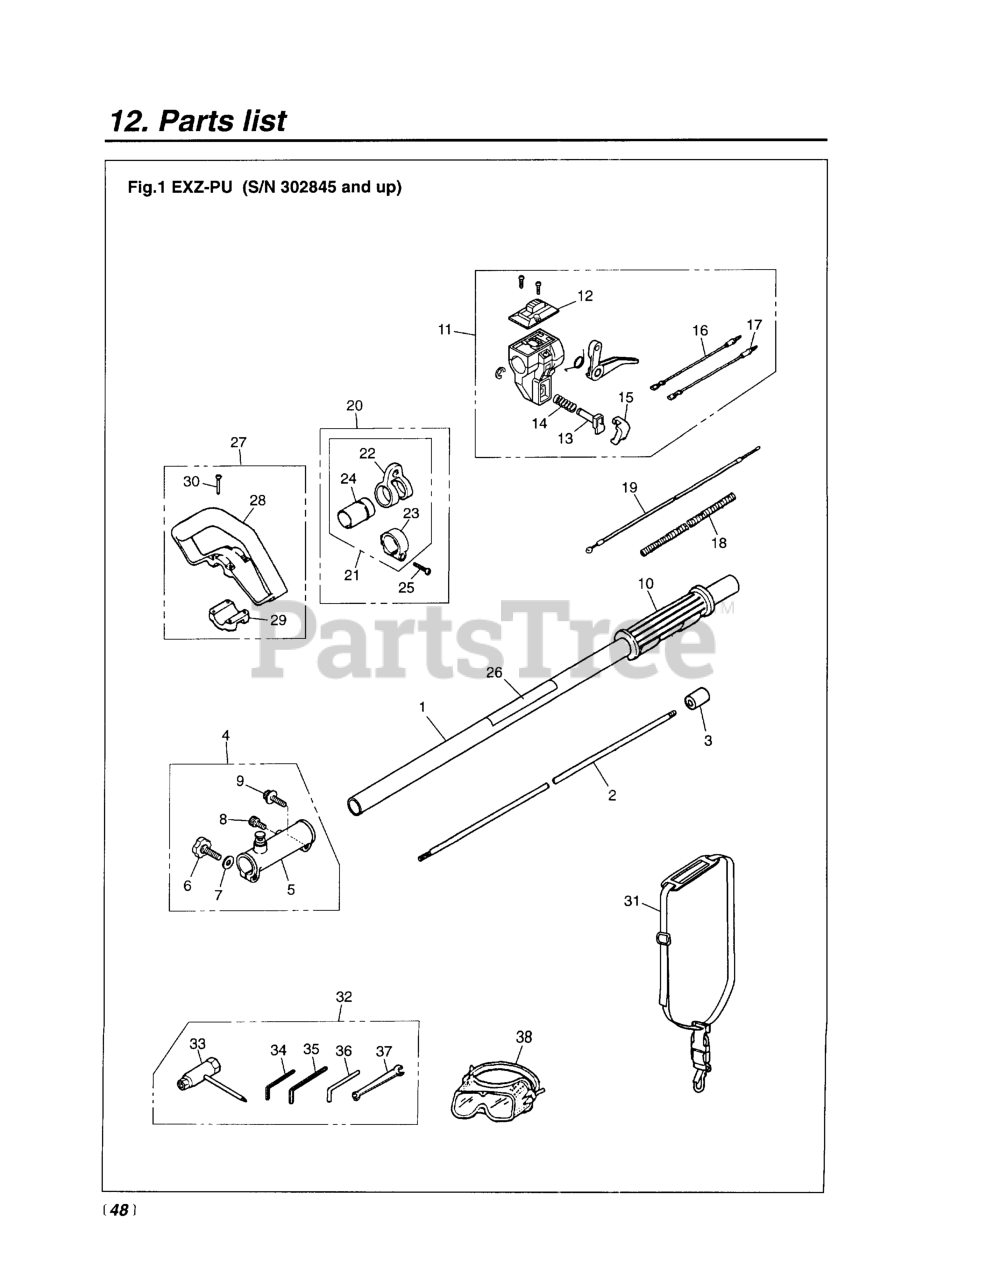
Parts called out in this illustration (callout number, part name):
1	PIPE COMPLETE
2	SHAFT
3	SPACER
4	JOINT, PIPE ASSY
5	JOINT
6	BOLT, KNOB
7	WASHER, M8 x 2.3 (RPLS -20823)
8	BOLT, M5 X 10
9	BOLT, M6 x 1.35
10	GRIP (RPLS 3577-32140 & 3220-
16	CORD (A), BLACK
17	CORD (B), RED
18	TUBE (RPLS 4900-72141)
19	CABLE (RPLS 5580-83100)
20	HANGER ASSEMBLY
21	HANGER COMPLETE
22	HANGER
23	CLAMP
24	SLEEVE
25	SCREW, M5 x 25
26	NAMEPLATE
27	HANDLE ASSEMBLY
28	HANDLE
30	SCREW, M5 x 35
31	STRAP ASSY.
33	SOCKET
34	WRENCH (TOOL)
35	WRENCH (TOOL)
36	BAR
37	SPANNER, 8 X 10 (RPLS 2540- )
38	GOGGLE
